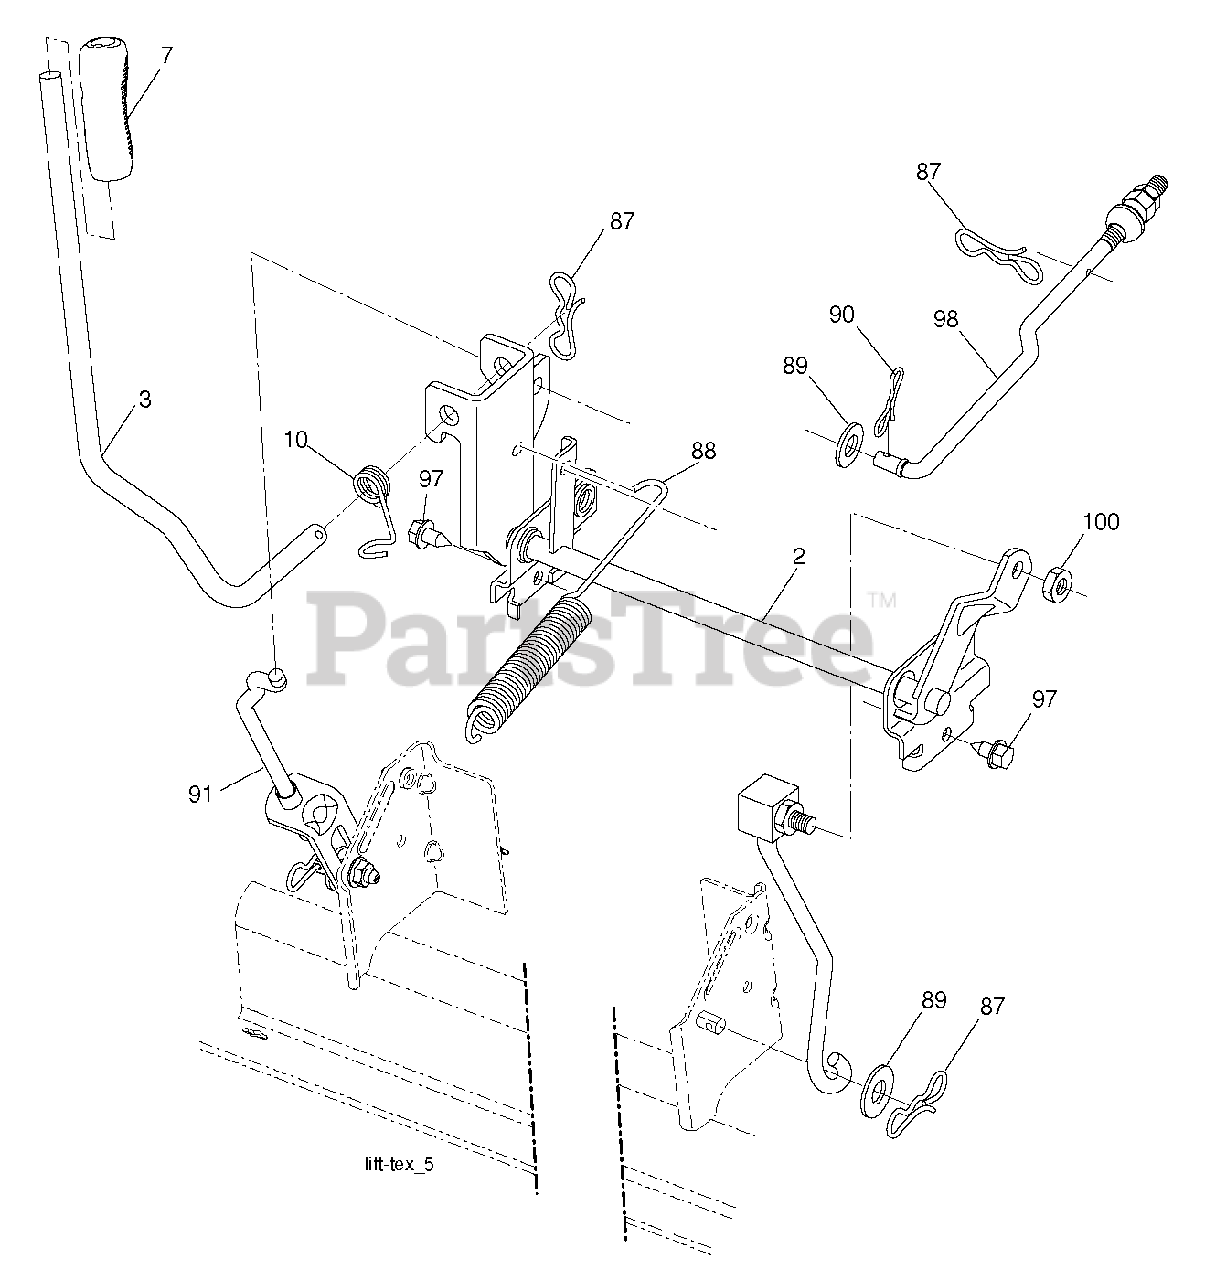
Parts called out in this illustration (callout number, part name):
2	SHAFT.ASM.LIFT.CROSS.H
3	LEVER.LIFT.HANDLE.GT
7	GRIP.HANDLE.LIFT.PVC.BLACK
10	SPRING.TORSION.LIFT.HANDLE
87	PIN.COTTER.7/16.BOW TI
88	SPRING.LIFT.ASSIST
89	WASHER.CLEAR.ZINC
90	PIN.COTTER.5/16.BOW TI
91	LINK.ASM.LIFT.REAR
97	SCREW, 3/8-16X3/4
98	LINK.ASM.SUSP.FRONT.MW
100	LOCKNUT
